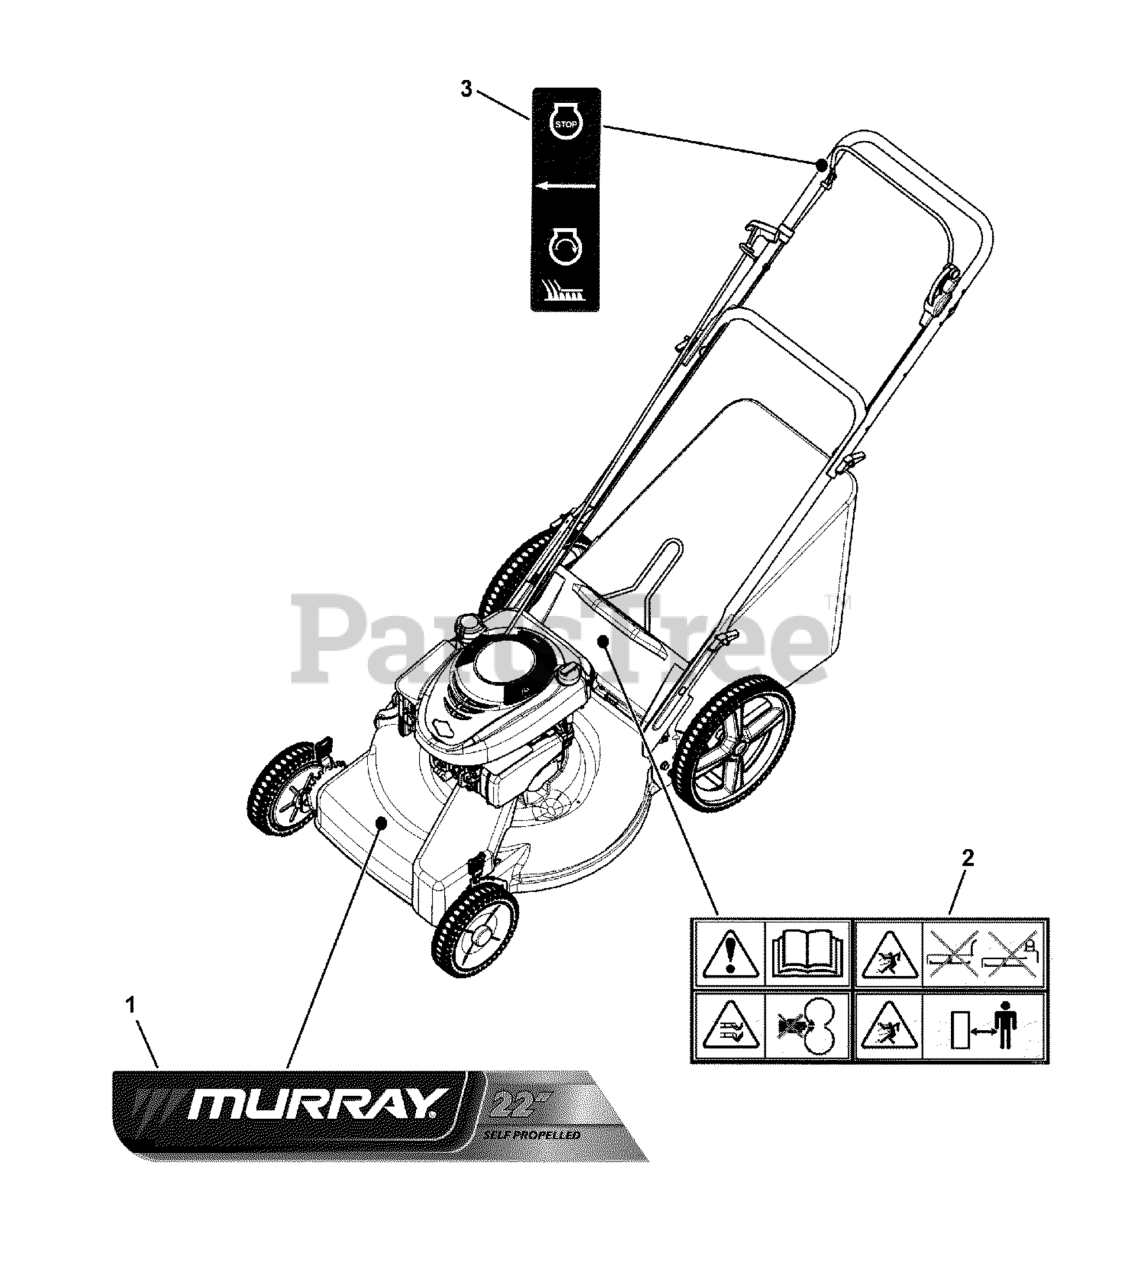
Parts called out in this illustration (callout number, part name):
1	DECAL, Murray Logo, Deck
2	DECAL, Warning, Euro, Multi-Panel
3	DECAL, OPC Bail International Symbol
